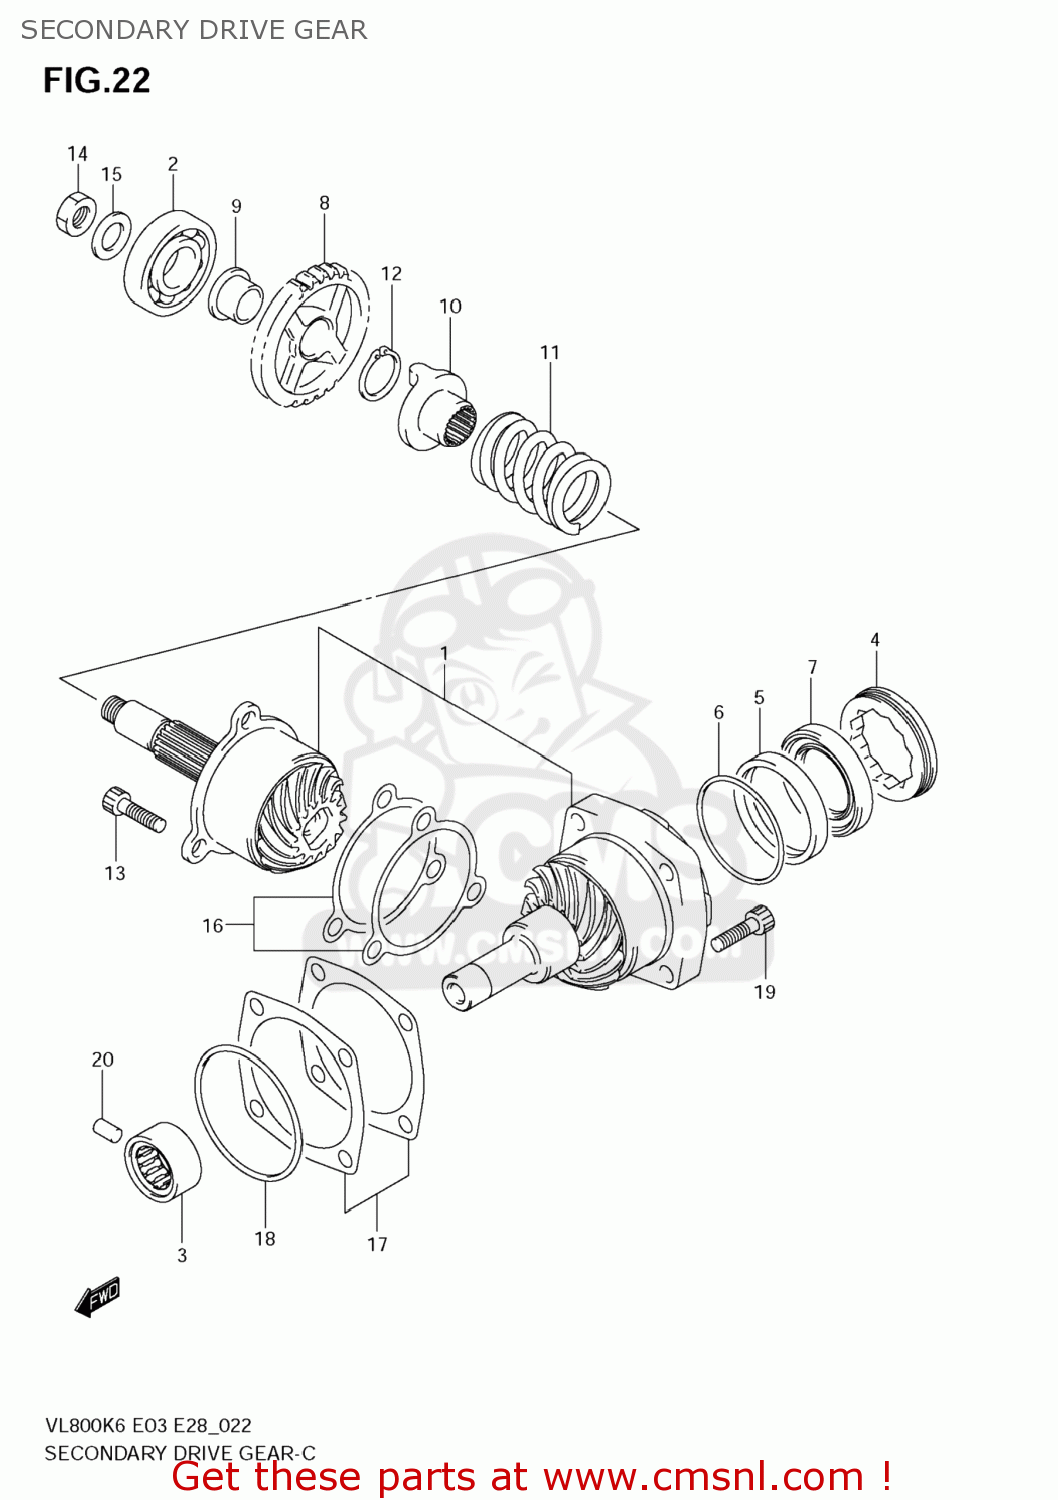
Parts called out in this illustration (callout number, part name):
1	GEAR & HOUSING SET,SECONDARY
2	BEARING(20X52X15)
3	BEARING(20X34X16)
4	STOPPER,SEC DRIVEN BEARING
5	HOUSING,OIL SEAL
6	O RING(D:1.2,ID:59.6)
7	SEAL,OIL(38X54X8.5)
8	GEAR,REDUCTION DRIVEN(NT:30)
9	BUSH,REDUCTION DRIVEN GEAR
10	DOG,OUTPUT CAM
11	SPRING
12	CIRCLIP
13	BOLT(8X25)
14	NUT
15	WASHER(16X29X4)
16	SHIM SET,SEC DRIVE GEAR
17	SHIM SET,SEC DRIVEN HOUSING
18	O RING(D:2.1,ID:66.2)
19	BOLT(8X25)
20	PIN
